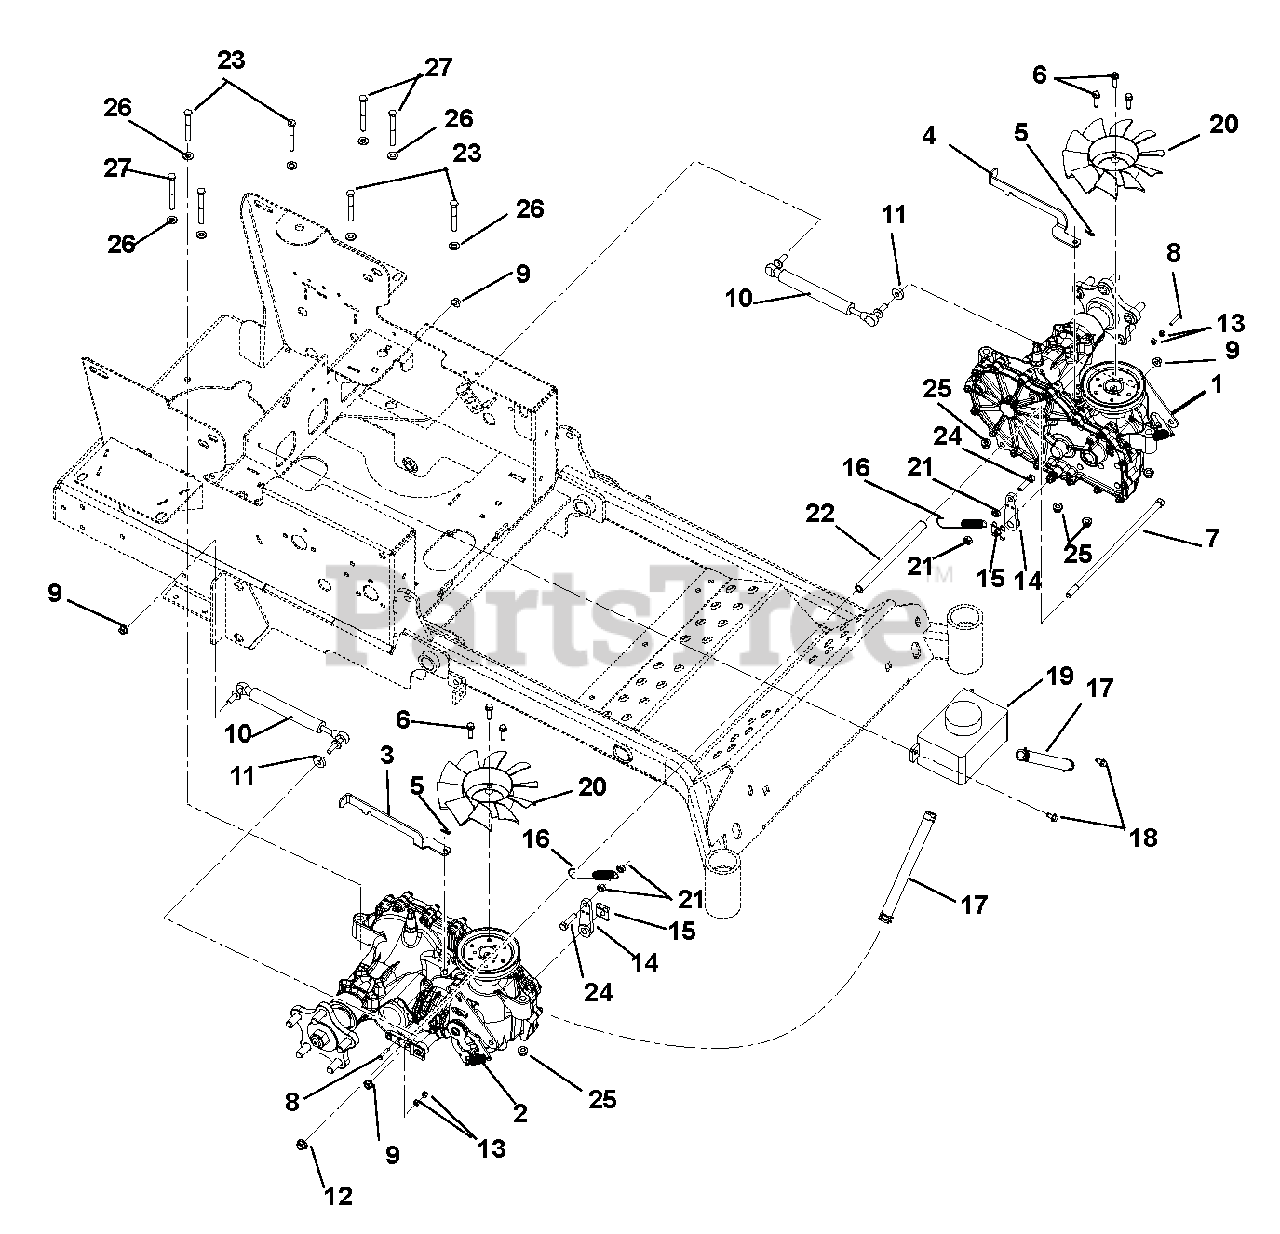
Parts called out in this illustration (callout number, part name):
1	TRANSAXLE, 3100 SERIES - LH
2	TRANSAXLE, 3100 SERIES - RH
3	RH DUMP VALVE LEVER - BLACK
4	LH DUMP VALVE LEVER - BLACK
5	PIN-HAIR INT .06X.18X.77
6	@SCR-TAP .25-20X1.00 HWH TR YZ
7	BLT HEX, .38-16X11.00 GR5 YWZC
8	SCR-MCH 8-32X1.00 HWH YWZC
9	NUT, M8-1.25 WHIZ LOCK YWZC
11	WSHR-FL-STL .328X.87X.179 YWZC
12	@NUT-LK-NYL-FLG .38-16 YWZC
13	@NUT-LK-NYL 8-32 W/INSTR YWZC
14	ARM, BRAKE
15	CLIP, BRAKE ARM
16	SPRING, TENSION .056X.60X4.60
17	ASM, HYDRO OVERFLOW TANK HOSE
18	@SCR-TAP .25-20X.50 HWH TR YWZ
19	TANK, EXPANSION
20	FAN, 2800 SERIES COOLING
21	@NUT-LK-CTR .31-18 YWZC
22	SPCR,.406 ID X .630 OD X 7.724
23	@BLT-HEX .31-18X2.50 GR5 YWZC
24	@BLT-HEX .31-18X1.25 GR5 YWZC
25	@NUT-LK-NYL-FLG .31-18 YWZC
26	@WSHR-FL-STL.344X.688X.065YWZC
27	@BLT-HEX .31-18X3.00 GR5 YWZC
